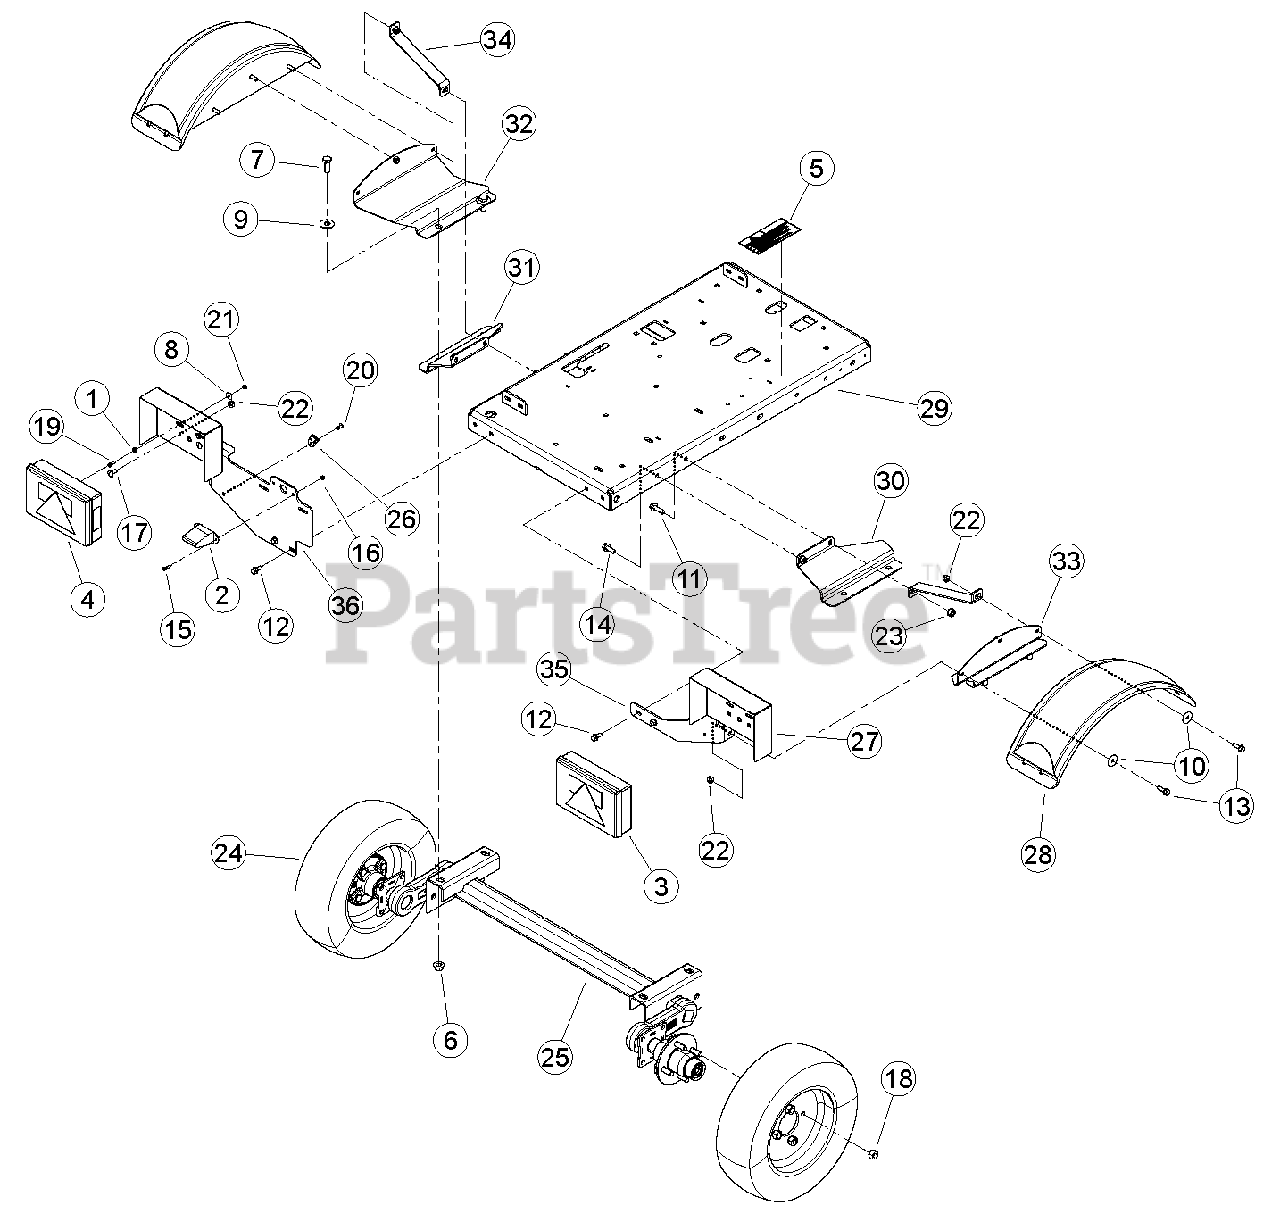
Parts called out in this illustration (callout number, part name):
1	GROMMET, 1/4 X 5/8 RUBBER
2	LIGHT, LICENSE PLATE
3	LIGHT, TAIL RH
4	LIGHT, TAIL LH
5	DECAL, MUTILINGUAL MANUAL
6	NUT, 1/2" SERRATED FLANGE
7	BOLT, 1/2 X 1-1/4" GR5 HHCS NC ZP
8	WASHER, 1/4" FLAT ZP
9	WASHER, 1/2" FLAT Z
10	WASHER, 5/16" FENDER ZP
11	BOLT, 3/8 X 1-1/4 FLANGE NC
12	BOLT, 5/16 X 3/4 FLANGE NC
13	BOLT, 5/16 X 1 FLANGE NC
14	BOLT, 3/8 X 1 FLANGE NC
15	SCREW, #10 X 3/4 HEX TAP SC
16	NUT, 8-32 NYLOCK
17	BOLT, 5/16X3/4 GR5 CRG NC ZP
18	NUT, 1/2-20 WHEEL
19	BOLT, 10-24 X 3/4" HHCS GR8 PLAIN
20	RIVET, AL BLIND 1/4 X 3/4 DOME HEAD
21	NUT, #10-24 K-LOCK ZP
22	NUT, 5/16-18 NYLOCK FLANGE
23	NUT, 3/8-16 NYLOCK FLANGE
24	ASSEMBLY, 4.80-8 TIRE + WHEEL
25	AXLE, 1000LB TORSION
26	CLAMP, CABLE MOUNT
27	BRACKET, LIGHT
28	FENDER, BLACK PLASTIC DRILLED
29	WELDMENT, CHIPPER TRAILER
30	SUPPORT, AXLE FENDER RH
31	SUPPORT, AXLE FENDER LH
32	SHEET, MOUNT FENDER LH
33	SHEET, MOUNT FENDER RH
34	BRACKET, FENDER SUPPORT
35	BRACKET, LIGHT RH
36	BRACKET, LIGHT LH
